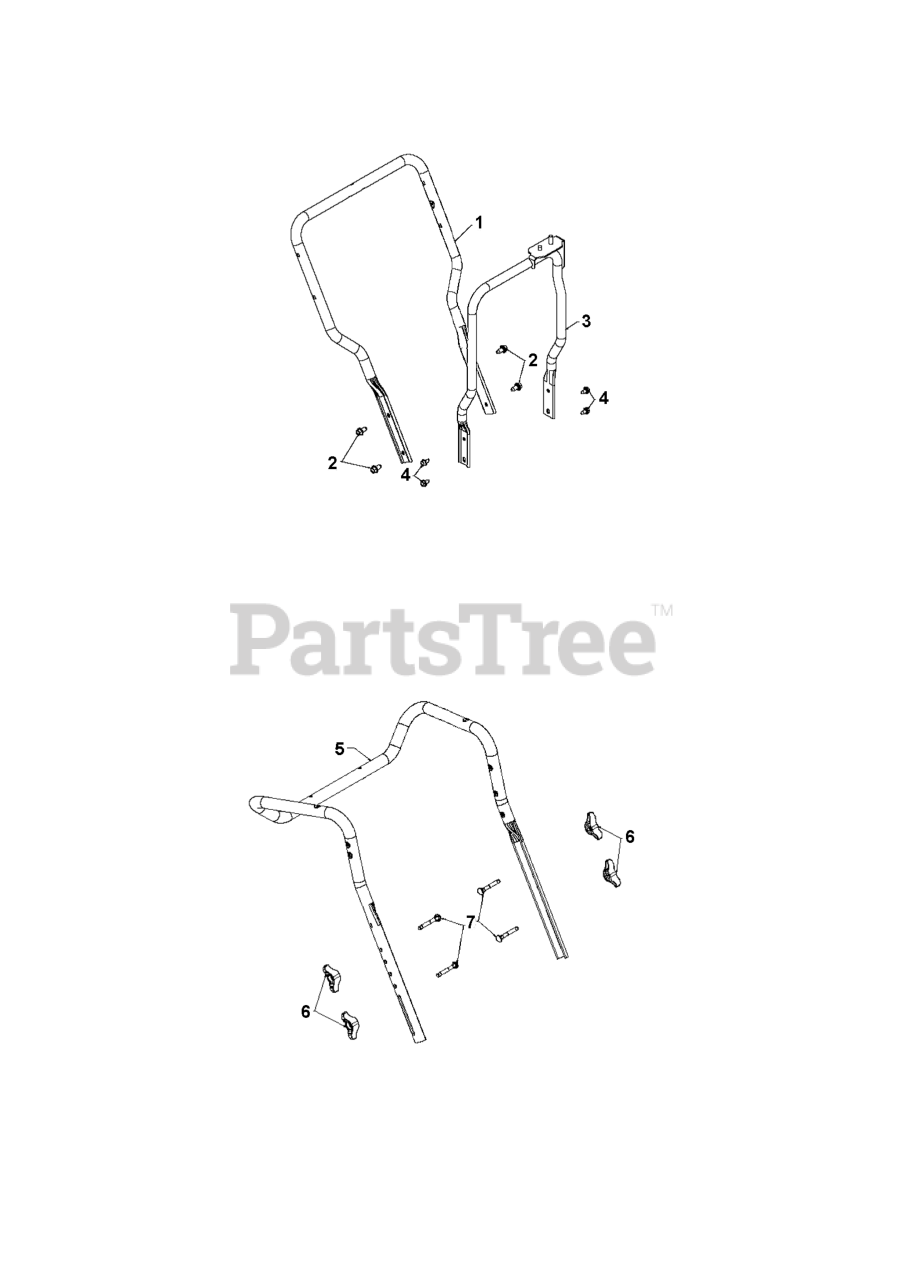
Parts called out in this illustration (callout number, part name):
1	CHASSIS WLDT ORANGE
2	NUT 3/8-16 NYLOC
3	HCS 3/8C X 1 1/4 GR5
4	BUSHING, BRONZE HOC
5	SNAP RING 1.25
7	BAR, THROWOUT OR
8	SB 3/8-16 X 3/8 SKT HD ZD
9	GUARD FILTER PAINTED
10	WASHER 3/8 FLAT
12	MOUNTING BLOCK CABLE TIE
13	TIE, PLASTIC
14	COVER, ASM, CENTER
15	SCREW 3/8C X 3/4 HEX CAP
16	LATCH, SHORT WING
17	HCS 1/2-13 X 1-1/4
18	NUT, 1/2-13 HEX FLG NYLOC ZD
19	GROMMET, BUMPER
20	RHSNB 3/8-16 x 2¾
21	NUT 3/8C WHIZ
22	NUT 3/8-16
23	BOLT 3/8-16 X 1.0
24	SUPPORT PLATE, P. BRAKE RH BLK
25	HCS 3/8-16 X 7/8 GR 5 ZD
26	HCS3/8-16.X
27	BUMPER, OR
